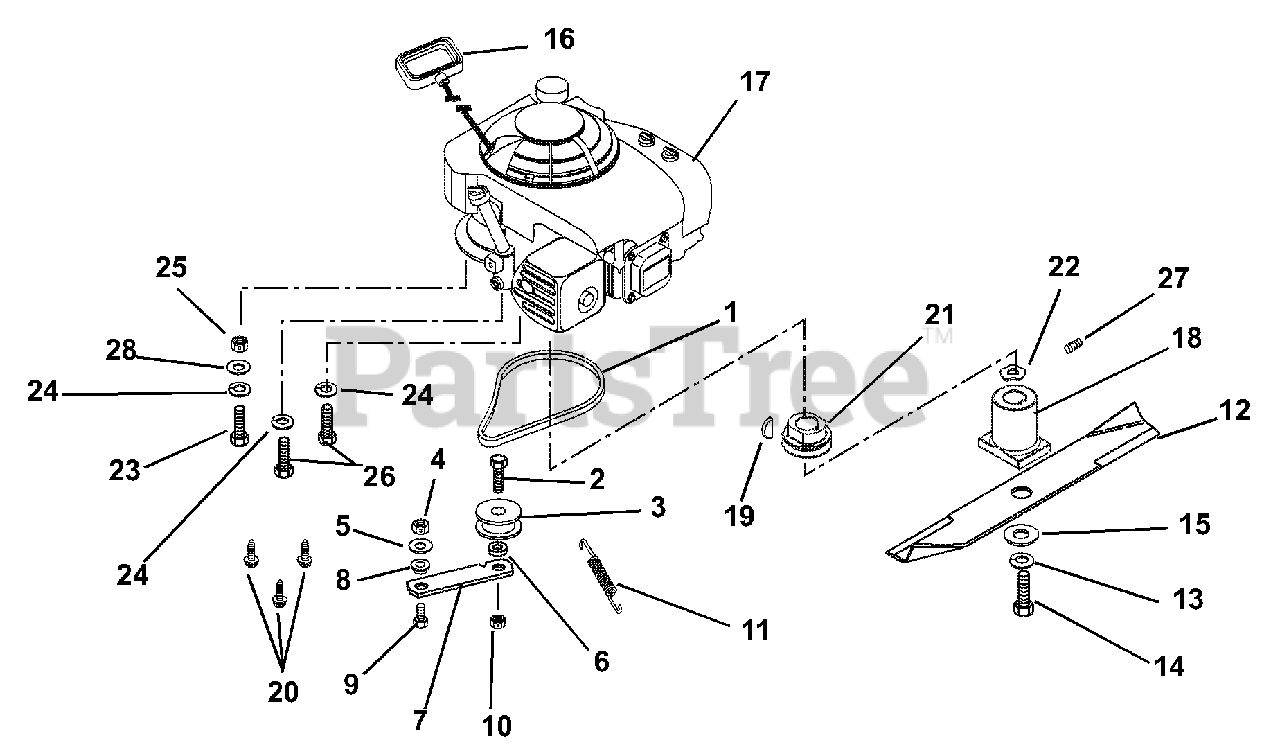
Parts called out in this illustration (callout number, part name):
1	V-BELT, 3L-COGGED
2	@BLT-HEX .44-14X1.50 GR5 YWZC
3	IDLER-FLAT 1.75 X .47
4	@NUT-LK-CTR .31-18 YWZC
5	@WSHR-FL-STL.344X.688X.065YWZC
6	BSHG-SLV .469 X .750 X .430
7	IDLER ARM
8	BSHG-FLG .325X.501X.250X1.120
9	@BLT-HEX .31-18X.75 GR5 YWZC
10	@NUT-LK-CTR .44-14 YWZC
11	SG-TENS .043X.44X3.31 WLD 5.8
12	BLADE, 21" LM MULCHING
12	21" MOWER BLADE
12	BLADE, 21" MOWER TUNGSTEN
13	@WSHR-LK .38X.094 REG YWZC
14	BLT-HEX .38-24 X 2.00 GR8 YWZC
15	WSHR-FL-STL .390X1.5X.125 YWZC
16	HANDLE, RECOIL START
17	ENGINE, B&S QUANTUM 6.5HP
17	ENG, B&S 6.75HP INTEK OHV RCL
17	ENGINE - HONDA 5.5 HP OHV
17	ENGINE, KAWASAKI 6.0 CONSUMER
18	ADAPTER-SINTERED IRON LM
18	ADAPTER - BLADE HUB
19	KEY-WDRF .156X.625X.25 SAE 6
20	@SCR-TAP .38-16X1.00 HWH TR YZ
21	PULLEY-SINTERED IRON LM
21	PULLEY - UNV DRIVE - STEEL
22	WASHER-WAVE .885X1.311X.125
23	BLT-HEX .31-24X1.50 GR5 YWZC
24	@WSHR-LK .31X.078 REG YWZC
25	NUT-HEX .312-24 YWZC
26	BLT-HEX .31-24X1.00 GR5 YWZC
27	SCR-SET .31-18X.38 SKHCUPDL
28	@WSHR-FL-STL.344X.688X.065YWZC
